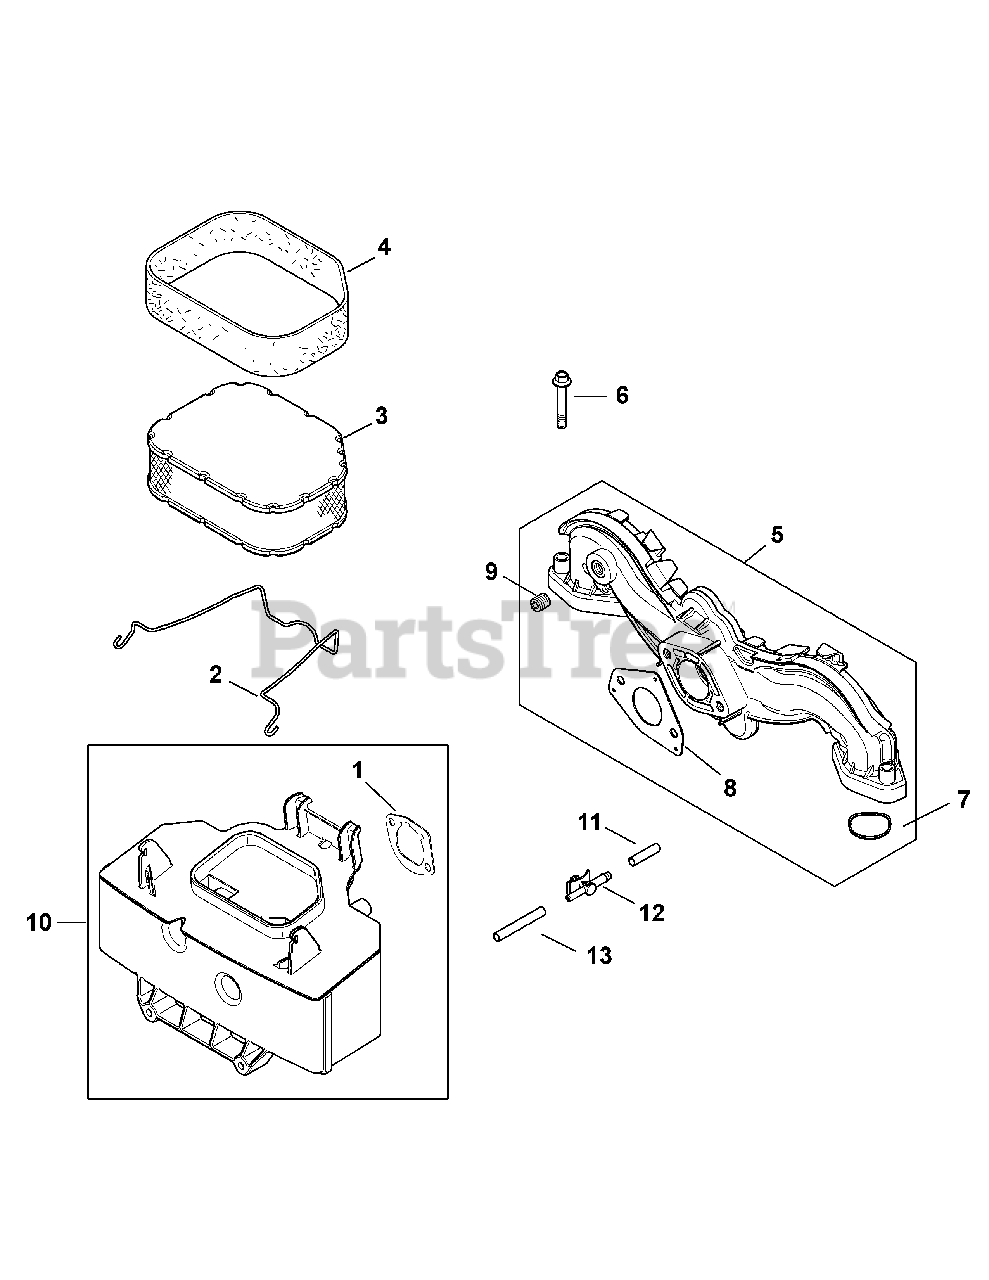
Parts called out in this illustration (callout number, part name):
1	Air Cleaner Base Gasket
2	Air Cleaner Element Latch
3	Air Filter & Pre-Cleaner Elements
4	Pre-Cleaner Element
5	Intake Manifold Kit
6	Flg. Screw, M6 x 1.0 x 40
7	O-Ring, Intake Port
8	Carburetor Gasket
9	Pipe Plug, 1/8"
10	Air Cleaner Base
12	Evaporative Connector
13	Evaporative Hose, 20"
